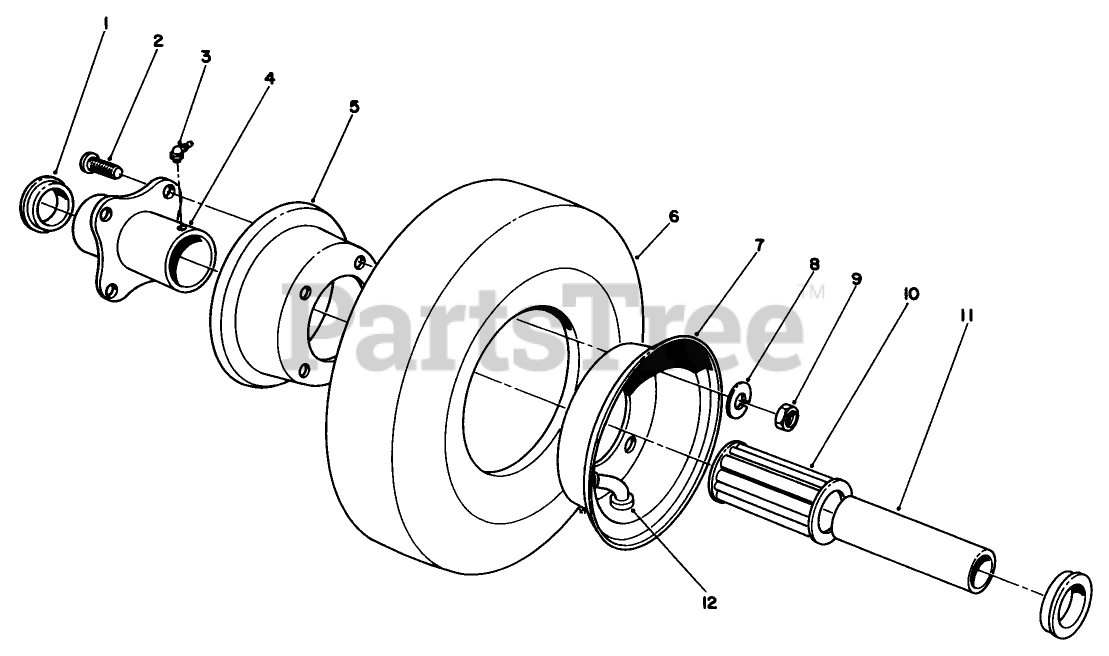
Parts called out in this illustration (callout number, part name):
1	RETAINER
2	WHEEL BOLT
3	FITTING-GREASE
4	HUB-CENTERED
5	WHEEL HALF-FEMALE
6	TIRE-8 Inch (4-PLY)
7	WHEEL HALF-MALE
8	WASHER-LOCK
9	NUT-HEX
10	BEARING-ROLLER
11	Bushing-Spanner
